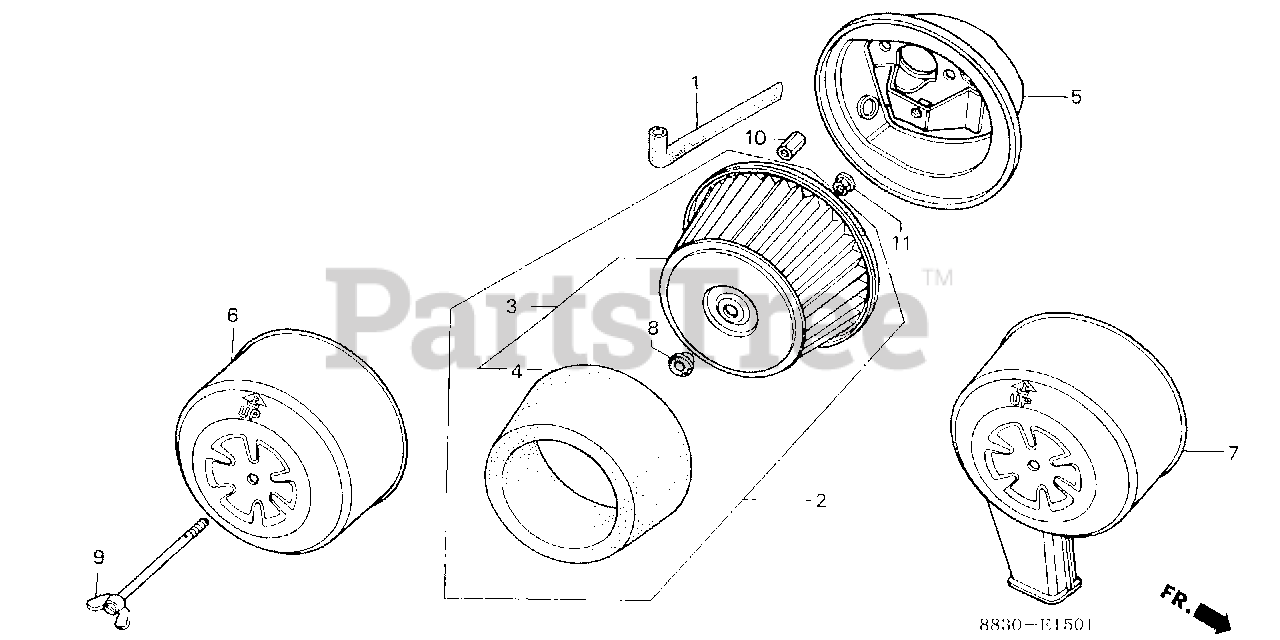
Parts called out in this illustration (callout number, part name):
2	ELEMENT, AIR CLEANER Use from Engine SN 1541113 to 2342662.
3	ELEMENT, AIR CLEANER Use from Engine SN 2342663.
4	ELEMENT B, AIR CLEANER Use from Engine SN 1541113.
